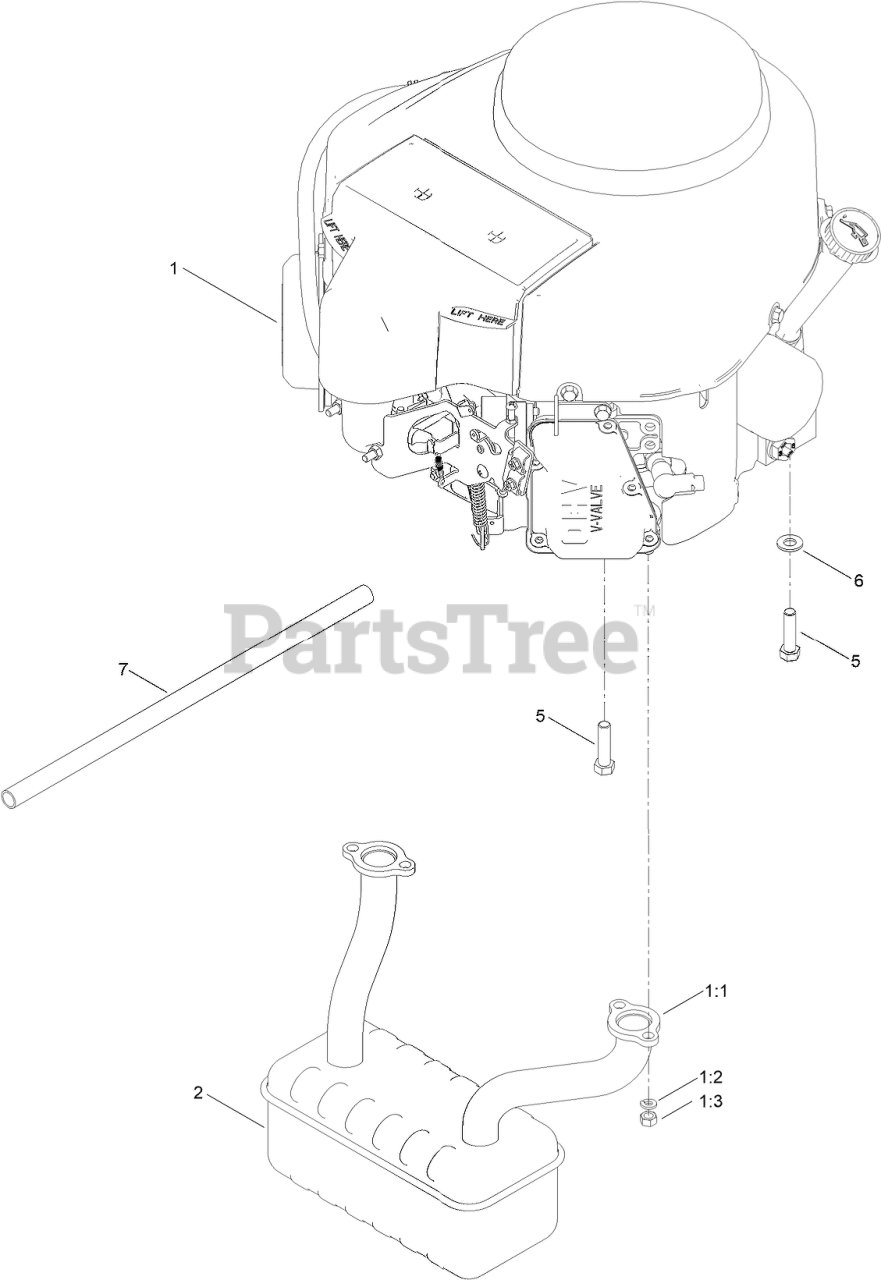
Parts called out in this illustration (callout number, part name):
1:1	GASKET-EXHAUST
1:3	WASHER-LOCK
2	MUFFLER
5	BOLT-HH
6	WASHER-FLAT
7	TUBE-DRAIN, OIL
